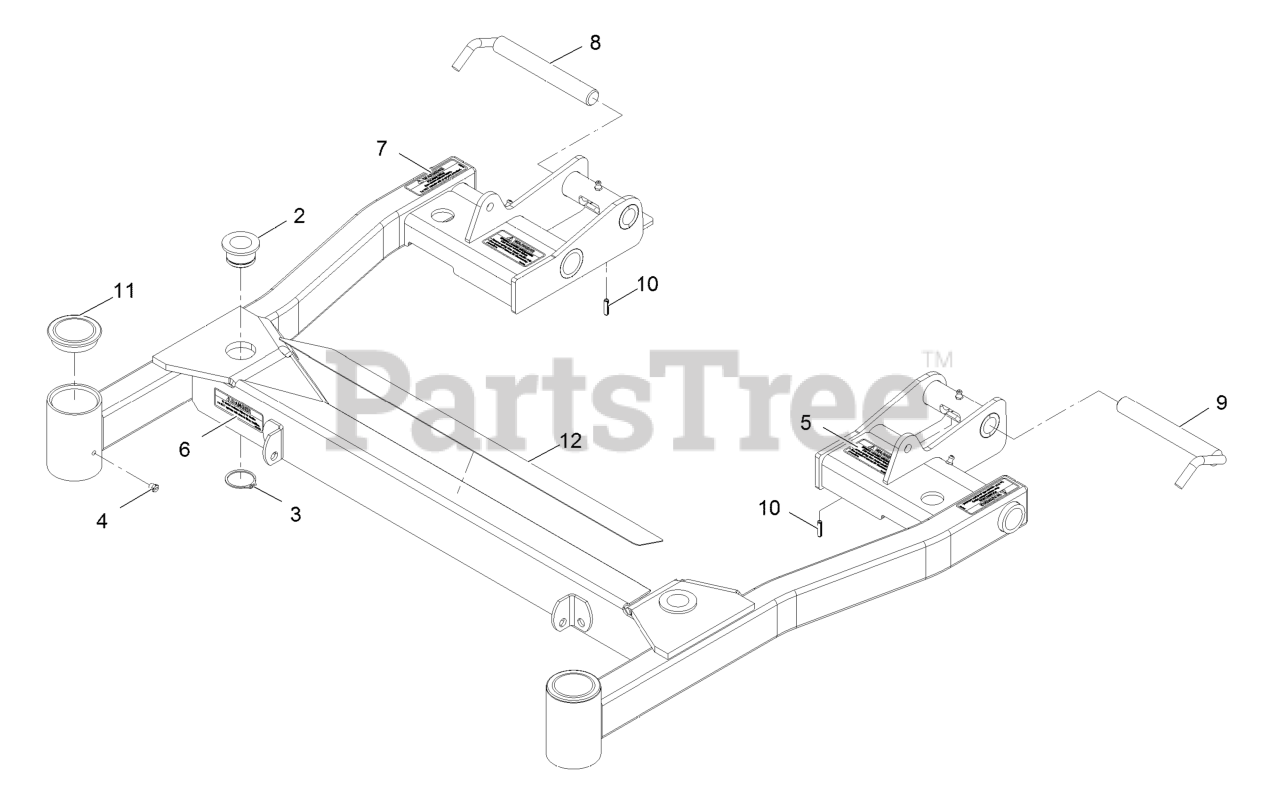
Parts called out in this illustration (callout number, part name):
2	BUSHING-SUPPORT, DECK
3	RING-RETAINING
5	DECAL-SPRING
6	DECAL-DANGER
7	DECAL-FOLDING DECK
8	LOCK-DECK, RH
9	LOCK-DECK, LH
10	PIN-SPRING
11	CAP-GREASE
12	PAD-SKID, ANTI
